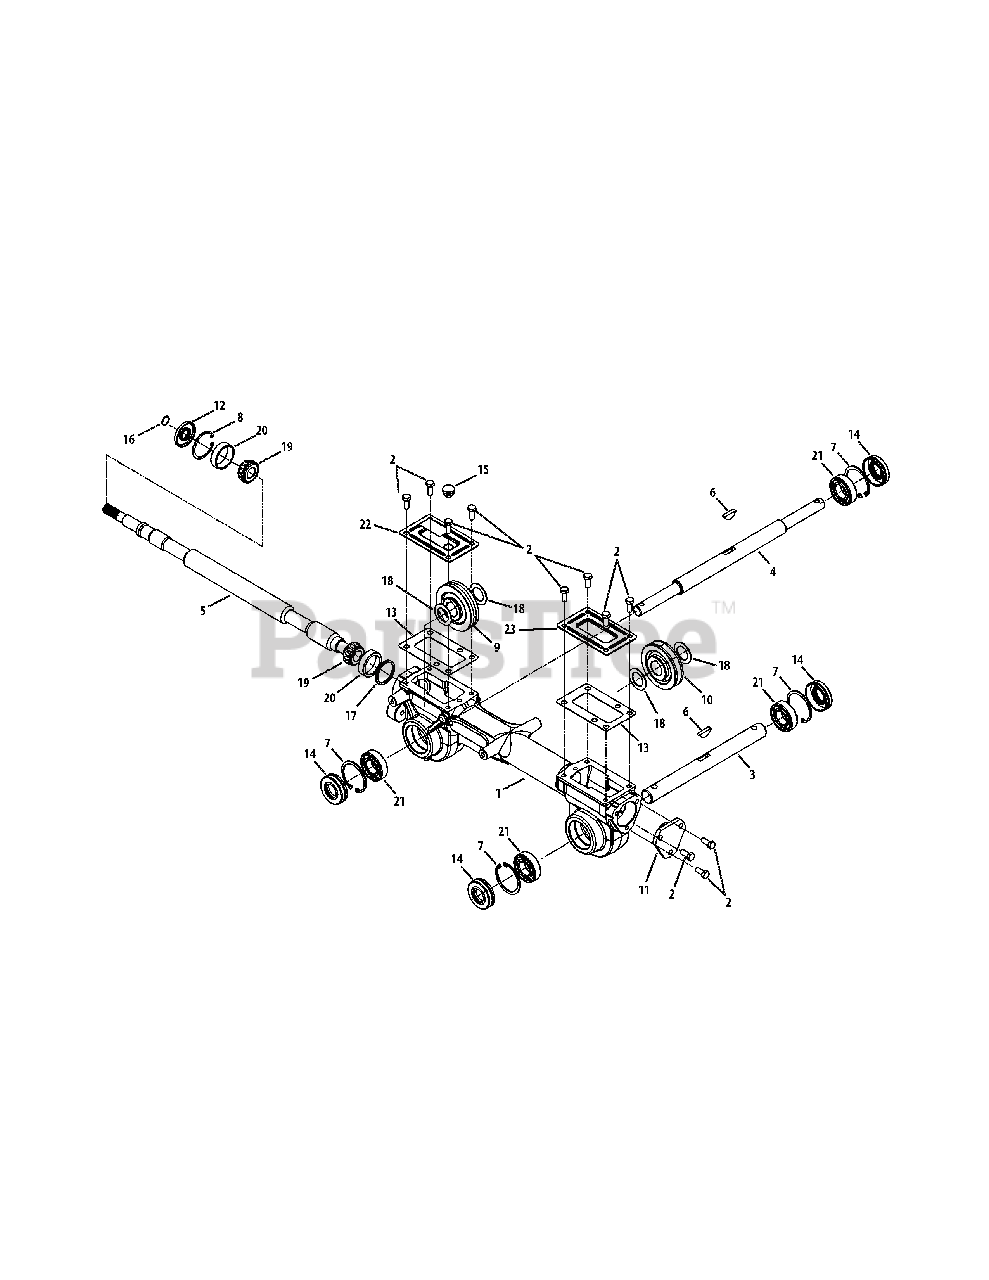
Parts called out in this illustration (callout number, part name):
1	Housing, Transmission
2	Hex Screw, 5/16-18, .75, Gr5
3	Shaft, Tiller
4	Shaft, Wheel
5	Shaft, Worm
6	Key, Hi Pro .25 x 1.062
7	Retaining Ring
8	Retaining Ring, Int
9	Worm Gear, 61t, RH
10	Worm Gear, 30t, LH
11	Bearing Cover
12	Seal, Oil, .750 Shaft x 1.783 Bore
13	Gasket, Gear Housing
14	Seal, Oil, 1.00 Shaft x 2.00 Bore
15	Rubber Plug, Oil
16	Wire Ring
17	Washer, Flat, 1.50 x 1.75 x .062
17	Washer, Flat, 1.50 x 1.75 x .005
17	Washer, Flat, 1.50 x 1.75 x .03
17	Washer, Flat, 1.50 x 1.75 x .010
18	Washer, Flat, 1.010 x 1.56 x .060
19	Cone Bearing
20	Bearing Cup
21	Ball Bearing
22	Cover, Transmission
23	Cover, Transmission
